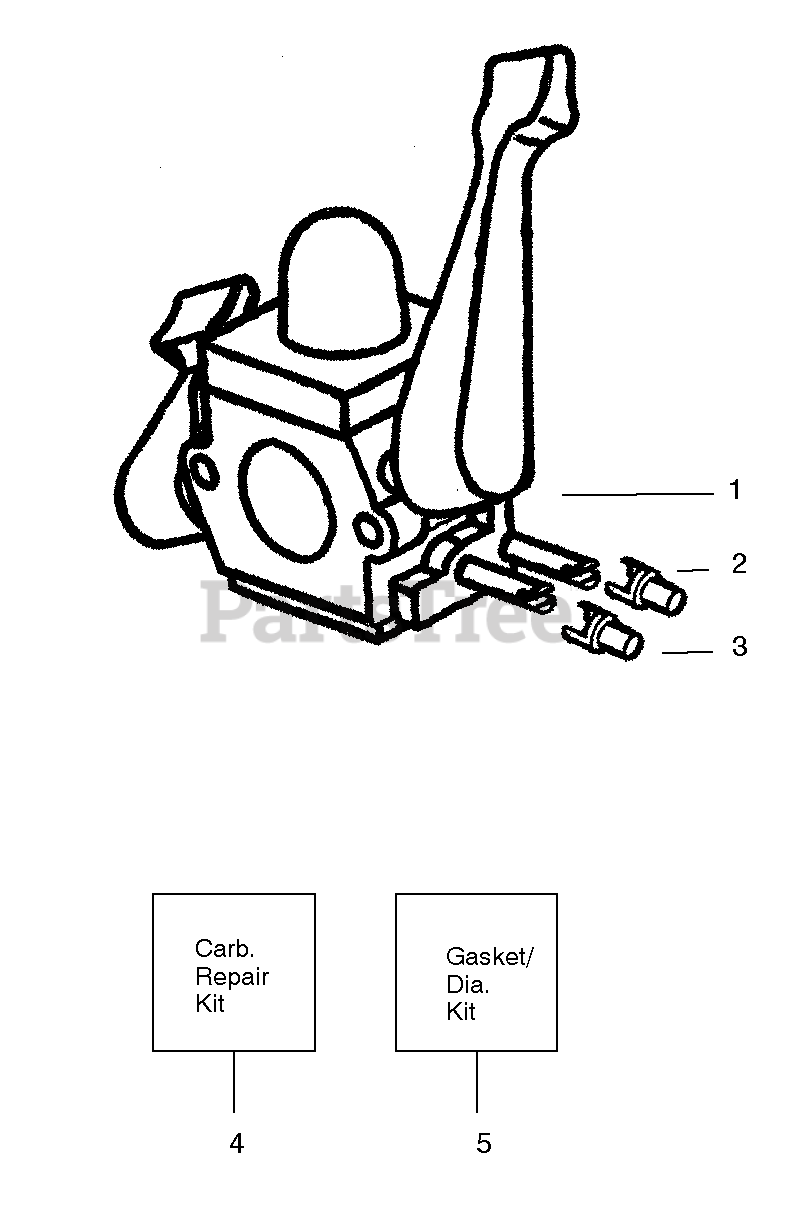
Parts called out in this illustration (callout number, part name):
1	Assy-Carb. Zama (C1Q-W11)
2	Cap-Limiter (high) brown
3	Cap-Limiter (low) tan
4	Kit-Carb. Repair
5	Kit-Carb. Gasket (Zama)
